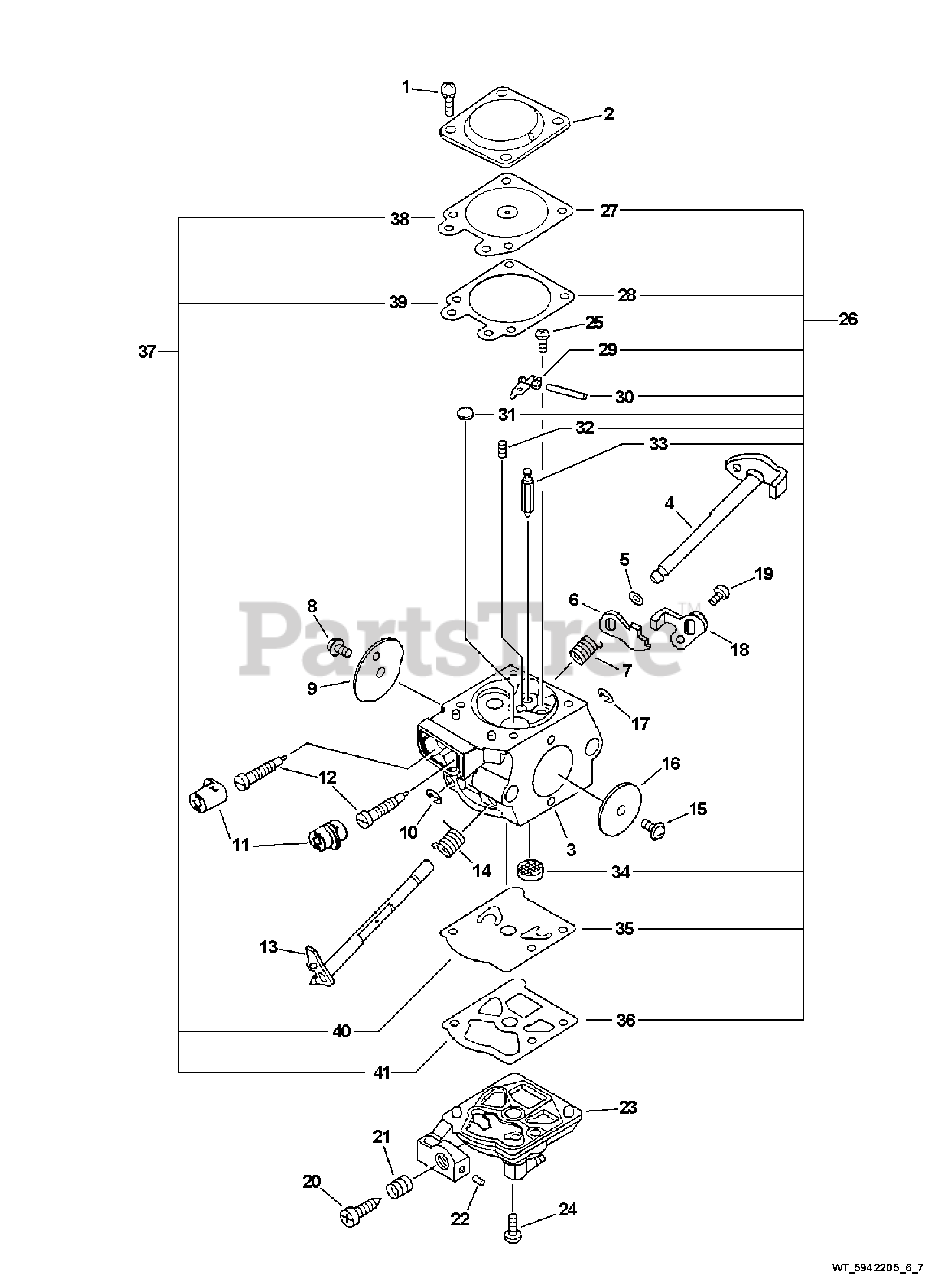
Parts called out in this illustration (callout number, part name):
2	COVER, METERING
3	BODY, CARBURETOR
4	SHAFT, CHOKE
6	LEVER, FAST IDLE
7	SPRING, CHOKE RETURN
9	VALVE, CHOKE
10	RING, RETAINING
11	CAP, LIMITER
12	NEEDLE - MIXTURE
13	SHAFT, THROTTLE
14	SPRING, THROTTLE RETURN
16	VALVE, THROTTLE
17	RING, RETAINING
18	LEVER, THROTTLE
20	SCREW, IDLE ADJUST
21	SPRING, IDLE ADJUST
23	COVER, PUMP
24	SCREW, PUMP COVER
25	SCREW, METERING LEVER PIN
26	REPAIR KIT
27	DIAPHRAGM, METERING
28	GASKET, DIAPHRAGM
29	LEVER, METERING
30	PIN, METERING LEVER
31	PLUG, WELCH
32	SPRING, METERING LEVER
33	VALVE, INLET NEEDLE
34	STRAINER
35	DIAPHRAGM, PUMP
36	GASKET, PUMP
37	DIAPHRAGM/GASKET KIT
38	DIAPHRAGM, METERING
39	GASKET, DIAPHRAGM
40	DIAPHRAGM, PUMP
41	GASKET, PUMP
